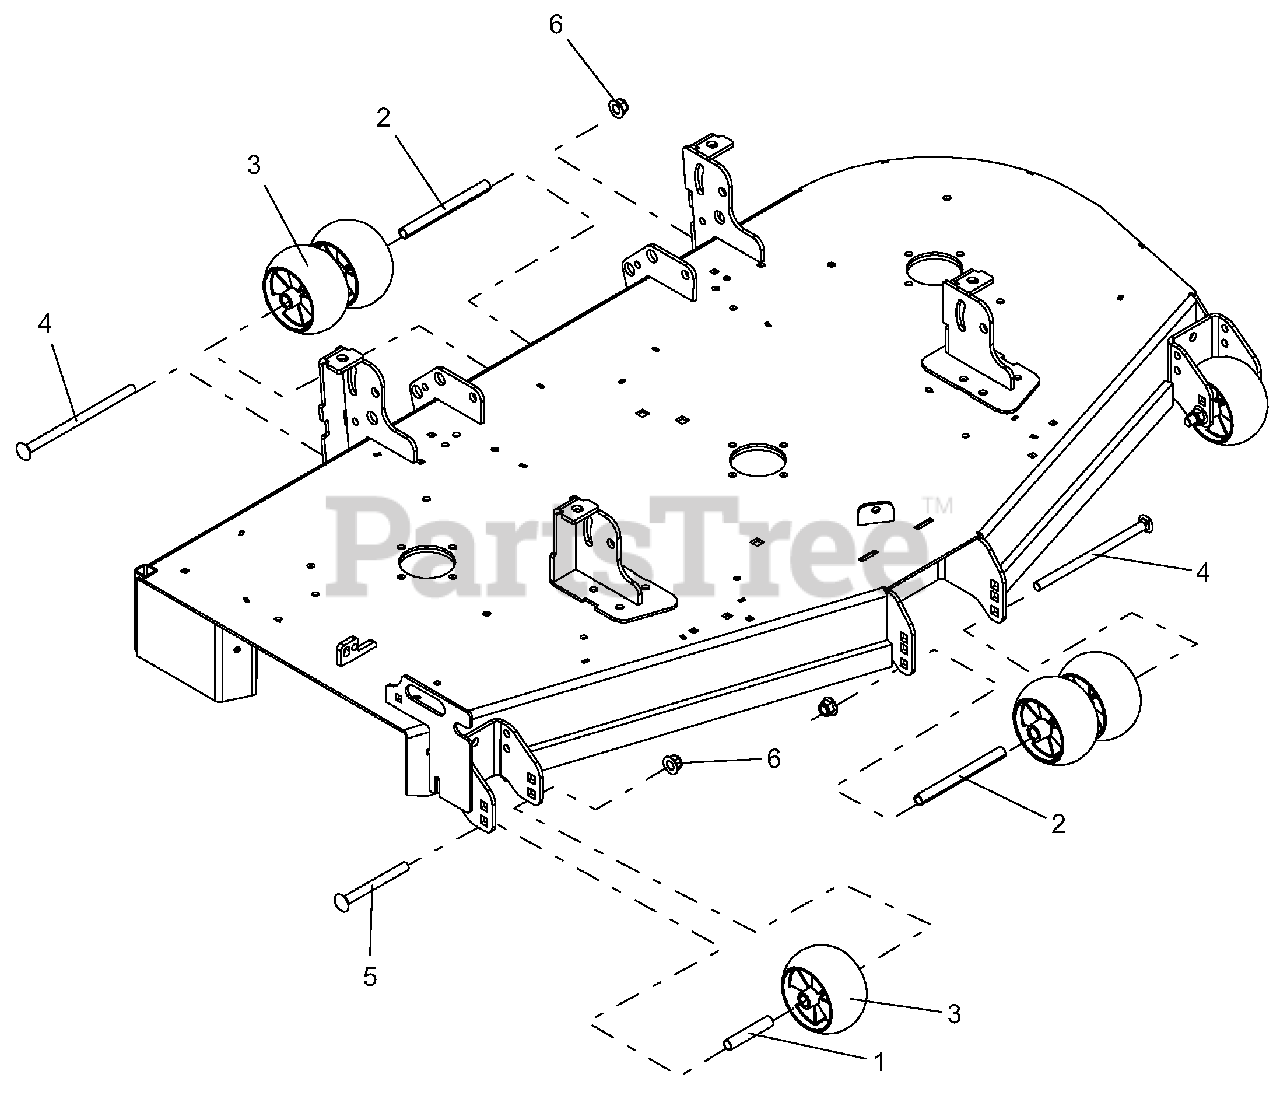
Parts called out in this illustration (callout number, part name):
1	SPACER, .510X.625X3.35
2	SPACER, .510X.625X6.70
3	ANTI-SCALP WHEEL - 5X3 CTR
4	BLT-RDHDSQNK .50-13X8.50 Y
5	BLT-RDHDSQNK .50-13X5.00 G5 YWZC
6	NUT-LK-NYL-FLG .50-13 YWZC
